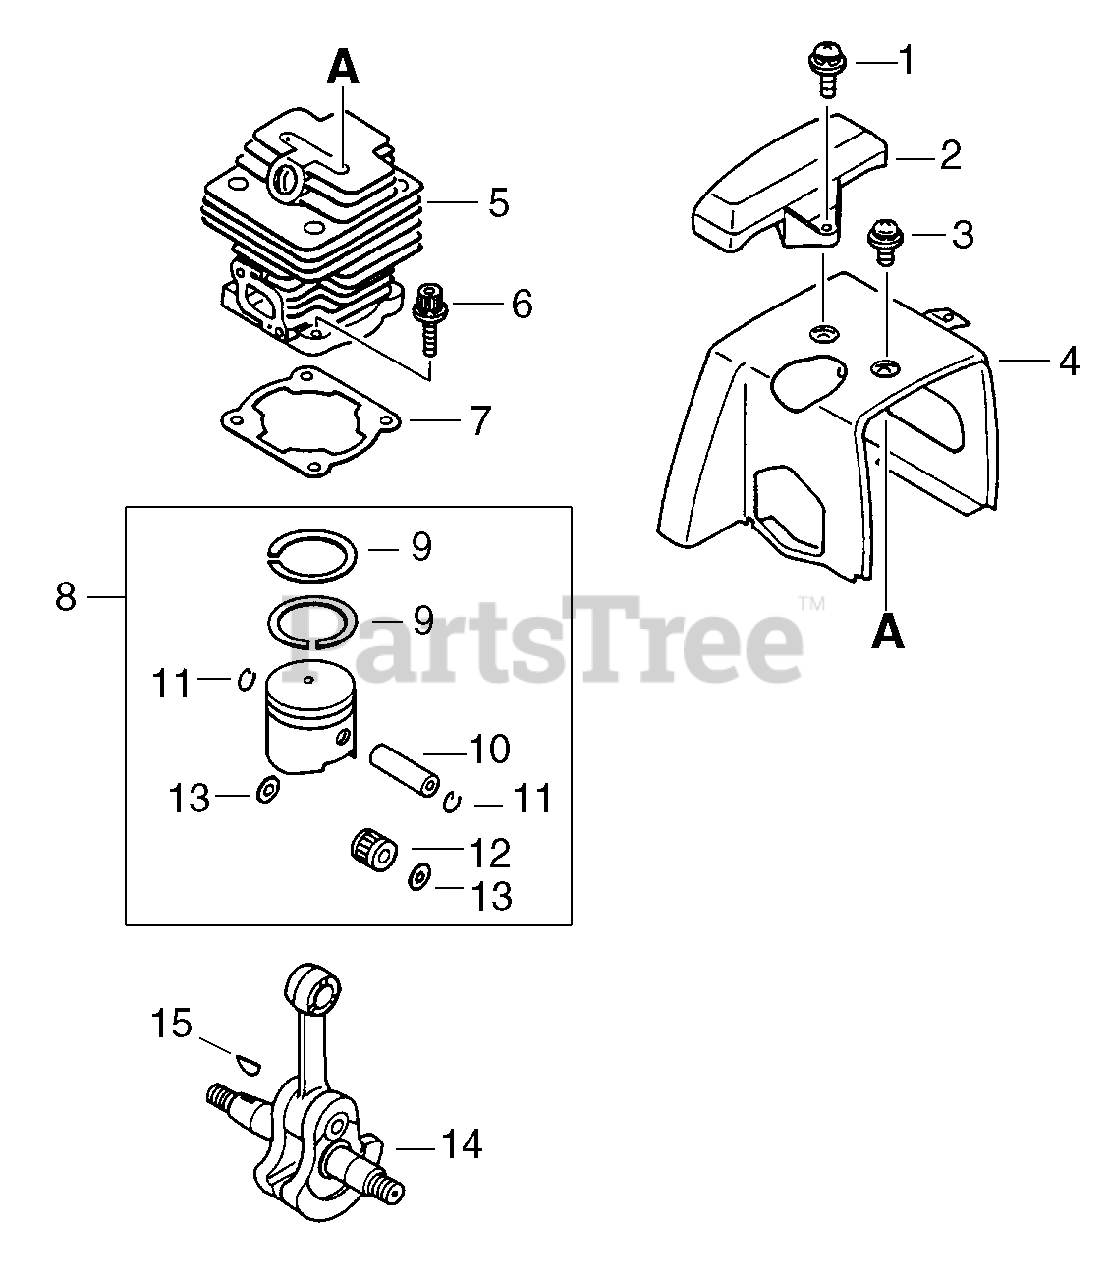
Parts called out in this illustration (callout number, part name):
1	SCREW - 5X14
2	GUARD - TOP
3	SCREW - 5X10
4	COVER, ENGINE
5	CYLINDER
6	SCREW - 5X20
7	GASKET, CYLINDER
8	PISTON KIT
9	RING, PISTON
10	PIN, PISTON
11	RING, RETAINING - 8
12	BEARING, NEEDLE
13	WASHER - 10
14	CRANKSHAFT ASSY
